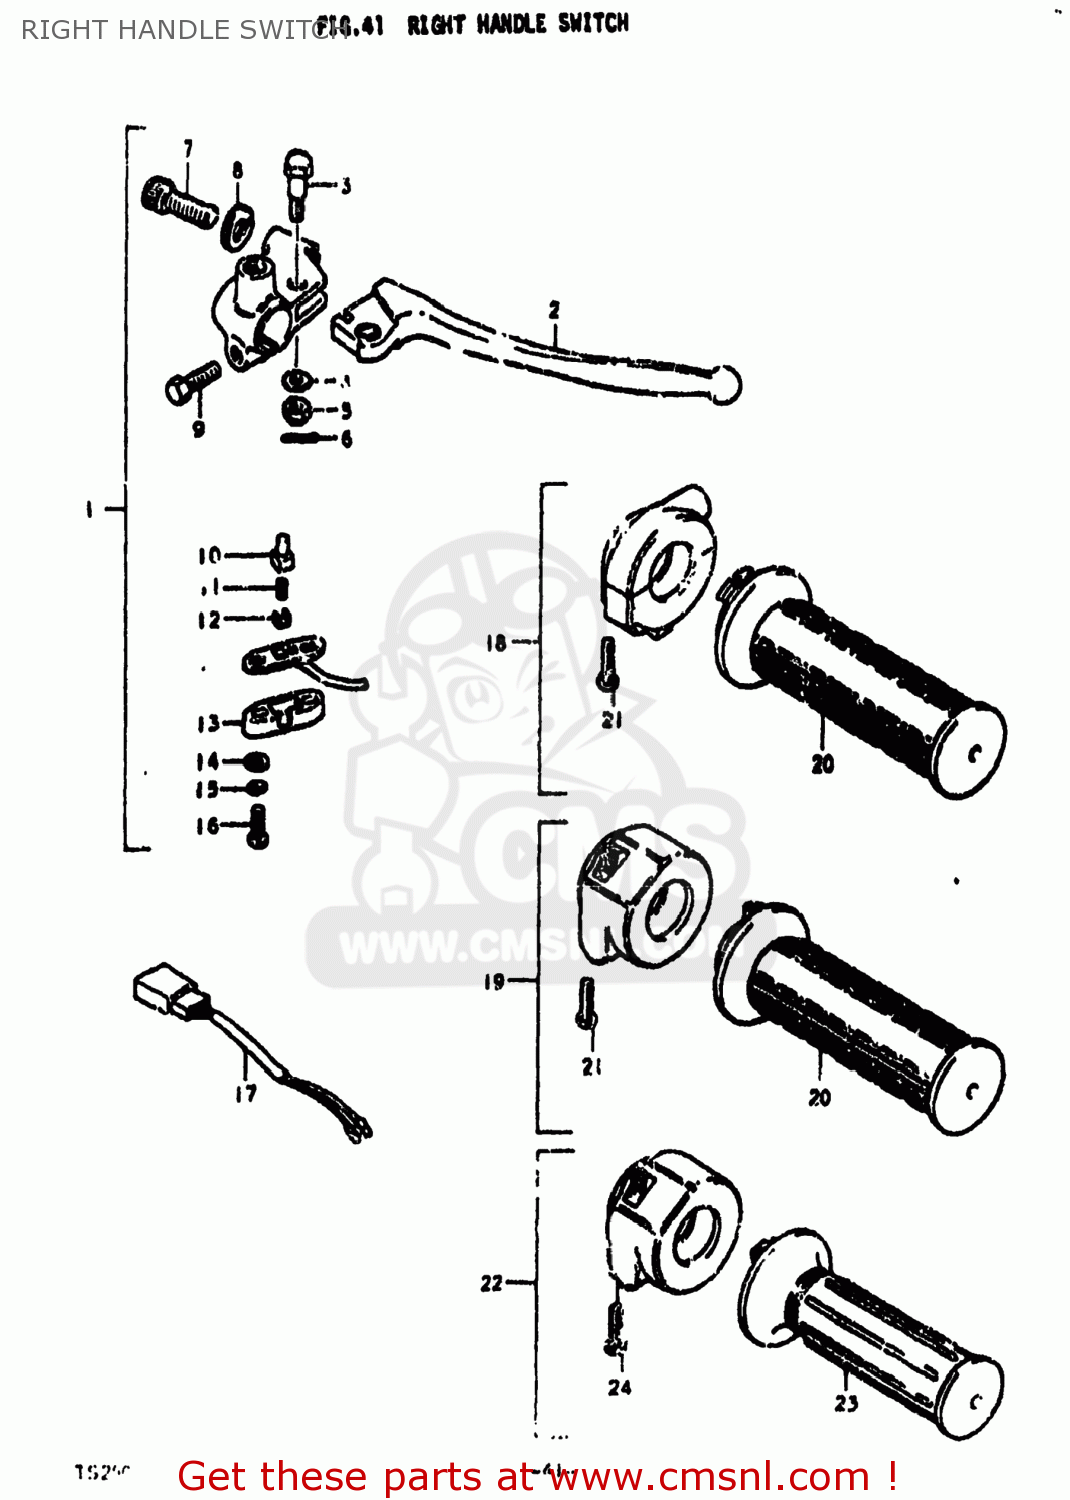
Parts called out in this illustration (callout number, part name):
1	LEVER ASSEMBLY,BRAKE
2	LEVER,BRAKE
3	BOLT,LEVER
4	WASHER,LOCK
5	NUT,LEVER FITTNG
6	COTTER PIN
7	ADJUSTER,CABLE
8	NUT,CABLE ADJUSTER
9	BOLT
10	HOLDER
11	SPRING
12	PLATE
13	COVER,FR BK TERMINAL BASE
14	WASHER
15	LOCK WASHER
16	SCREW
17	LEAD WIRE
18	GRIP ASSY,THROTTLE
19	GRIP ASSEMBLY,THROTTLE
20	GRIP,THROTTLE
21	SCREW
22	GRIP ASSEMBLY,THROTTLE
23	GRIP,THROTTLE
24	SCREW
